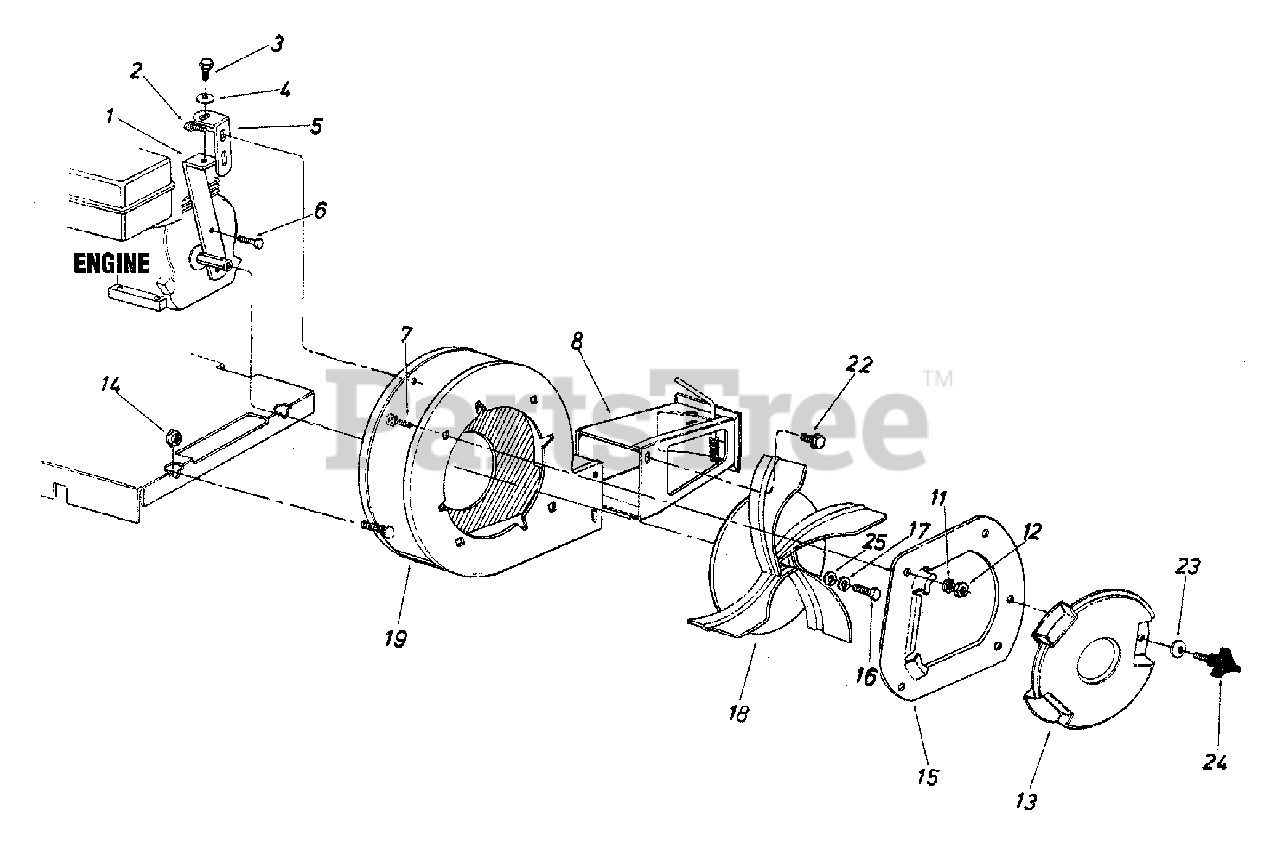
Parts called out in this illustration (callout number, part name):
3	Hex Screw 5/16-18 x .75
4	Special L-Washer 5/16" x .88 OD
7	Carriage Bolt 5/16-18 x .62
12	Hex Nut 5/16-18
13	Blower Guard
14	Hex Shoulder Nut .50"
17	Lock Washer 3/8
22	Hex Sems Bolt 5/16-18 x .62
23	Bell Washer .34 ID x .87 OD
24	Screw 5/16-18 x .75
25	Flat Washer
14563A-0637	PLATE ASSY-NOZZLE - POWDER BLACK (0637)
14563A-0691	PLATE ASSY-NOZZLE - BLACK JACK (0691)
